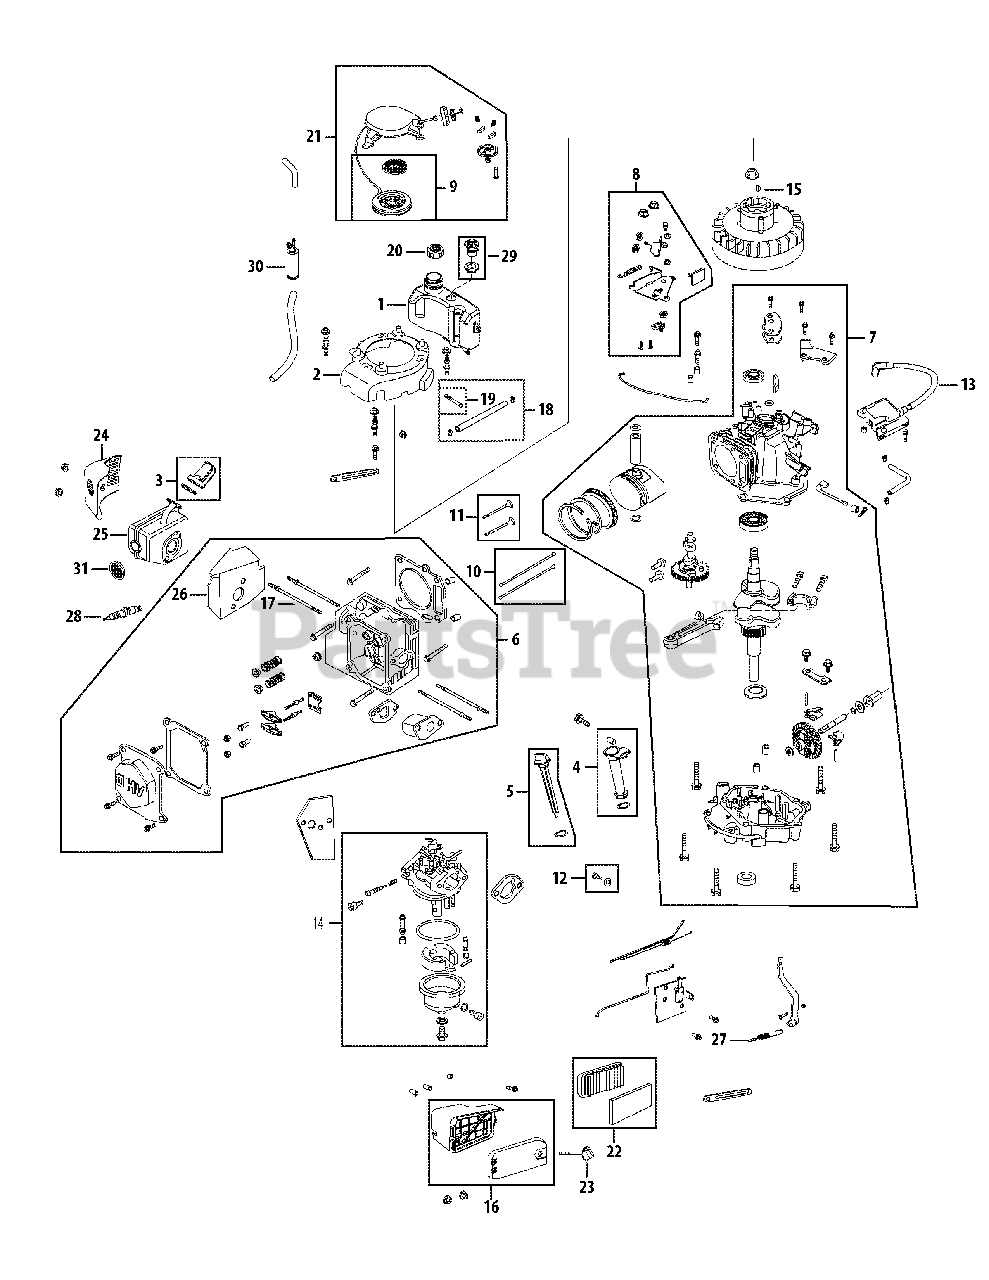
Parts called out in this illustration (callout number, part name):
1	Fuel Tank
2	Flywheel Shroud
3	Reed Valve Assembly
4	Oil Filler Tube Assembly
5	Dipstick Assembly
6	Cylinder Head Assembly
7	Short Block Assembly
8	Stop Switch and Brake Assembly
9	Recoil Spring and Pulley Assembly
10	Push Rod Kit
11	Valve Kit
12	Oil Drain Plug and Washer Assembly
13	Ignition Coil
14	Carburetor Assembly
15	Flywheel Key
16	Air Cleaner Housing Assembly Complete
17	Muffler Stud Assembly
18	Fuel Line Kit
19	Fuel Filter
20	Fuel Cap
21	Recoil Starter Assembly
22	Air Cleaner Kit
23	Air Cleaner Thumb Screw
24	Muffler Guard
25	Muffler
26	Muffler Gasket & Heat Shield
27	Governor Return Spring
28	Spark Plug
29	Roll Over Valve Assembly
30	Carbon Cannister
31	Spark Arrestor
